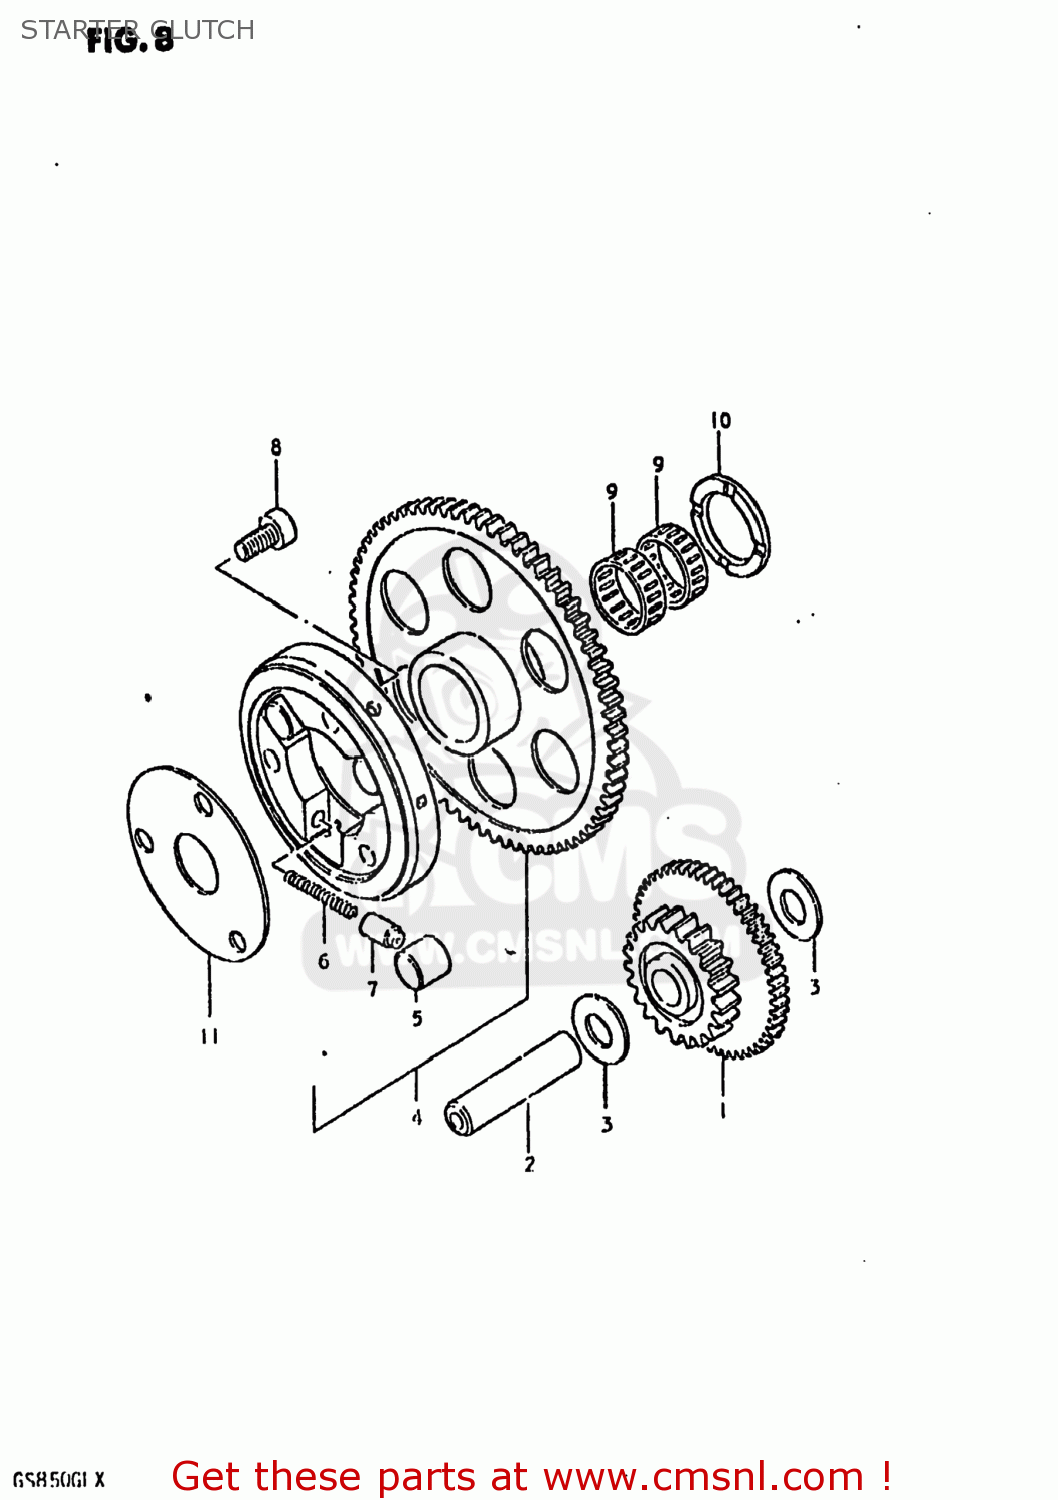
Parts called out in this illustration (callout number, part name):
1	GEAR,STARTER IDLE
2	PIN(7.4X13X56)
3	WASHER(13.3X25X0.85)
4	CLUTCH SET,STARTER
5	ROLLER(15X13)
6	SPRING
7	PIECE,PUSH
8	BOLT
9	BEARING(25X29X9.9)
10	WASHER(25X38X2.5)
11	SHIM,STARTER CLUTCH HUB
